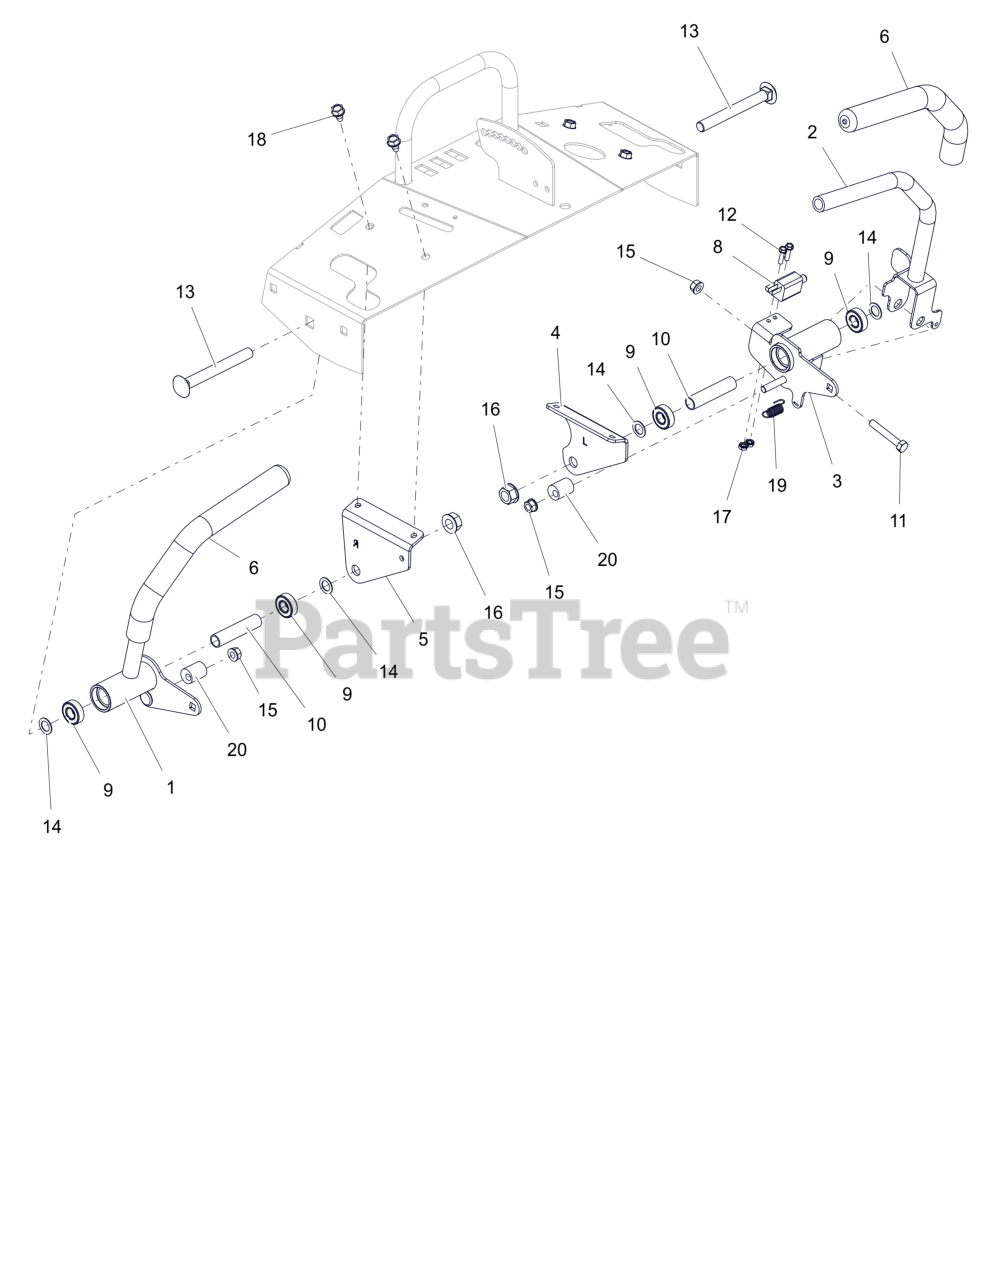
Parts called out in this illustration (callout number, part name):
1	WLDMT, RH DRIVE CONTROL (BLACK)
2	WLDMT, LH HANDLE ASM (BLACK)
3	WLDMT, LH DRIVE CONTROL (BLACK)
4	BRKT, LH DRIVE CONTROL MTG
5	BRKT, RH DRIVE CONTROL MTG
6	GRIP, HANDLEBAR
8	SWITCH- SINGLE POLE N.O.
9	BEARING, .500X1.125X.375
10	SPCR, .510 X .625 X 2.75
11	BLT, HEX .31-18X2.00 G5 ZCC
12	BLT, HWH #10-24X.75 ZCC
13	BLT,RHSN .50-13X4.50 G5 ZCC
14	WSHR-FL-STL 0.52X0.81X0.033 ZCC
15	NUT,LK-CTR-FLG .31-18 GF ZCC
16	NUT-LK-CTR-FLG .500-13 GG ZCC
17	NUT-KEPS 10-24
18	SCR,TAP .312-18X.50 HWH TR ZCC
19	SPRING, EXT. .043X.438X1.64
20	ECCENTRIC
